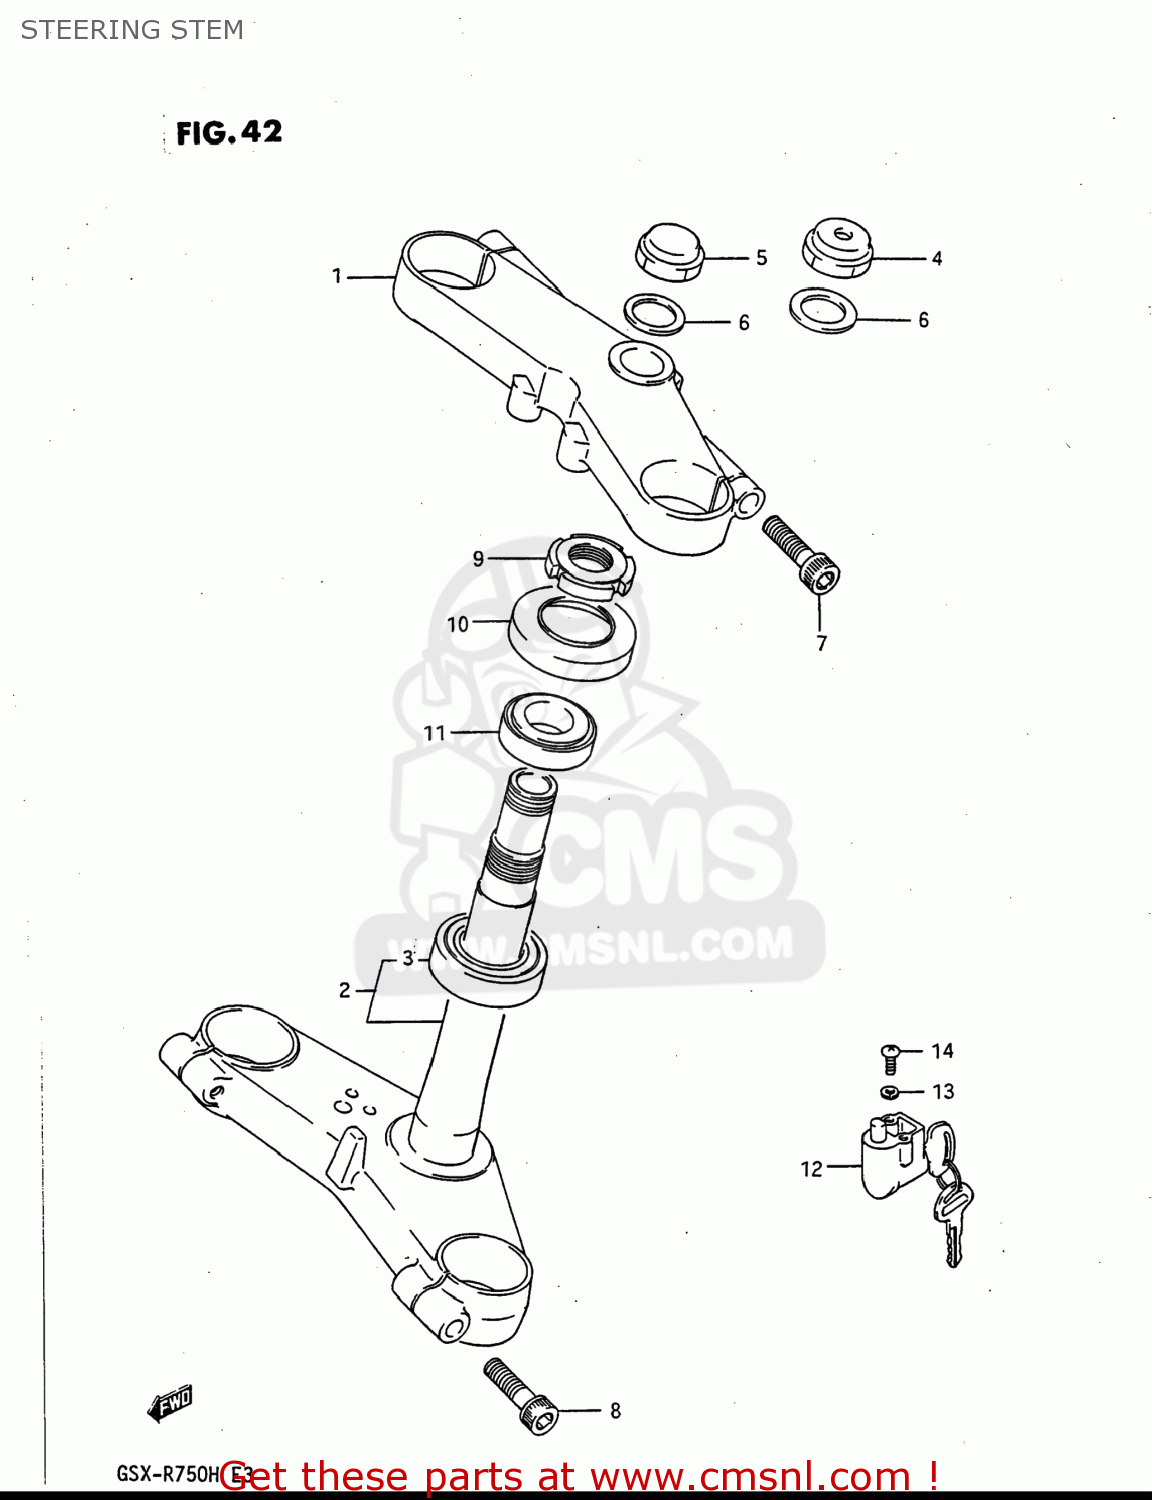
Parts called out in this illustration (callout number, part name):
1	STEM HEAD,STEERING
2	STEM,STEERING
3	BEARING
4	NUT,STEM HEAD
5	NUT,STEM HEAD
6	WASHER,STEERING STEM
7	BOLT,FORK INNER TUBE FITTING
8	BOLT ,10X40
9	NUT,STEERING STEM(25X44X10)
10	DUST SEAL,STEERING UPR
11	TAPER,ROLLER BEARING
12	LOCK ASSY,STEERING
13	LOCK WASHER
14	SCREW 5X20
